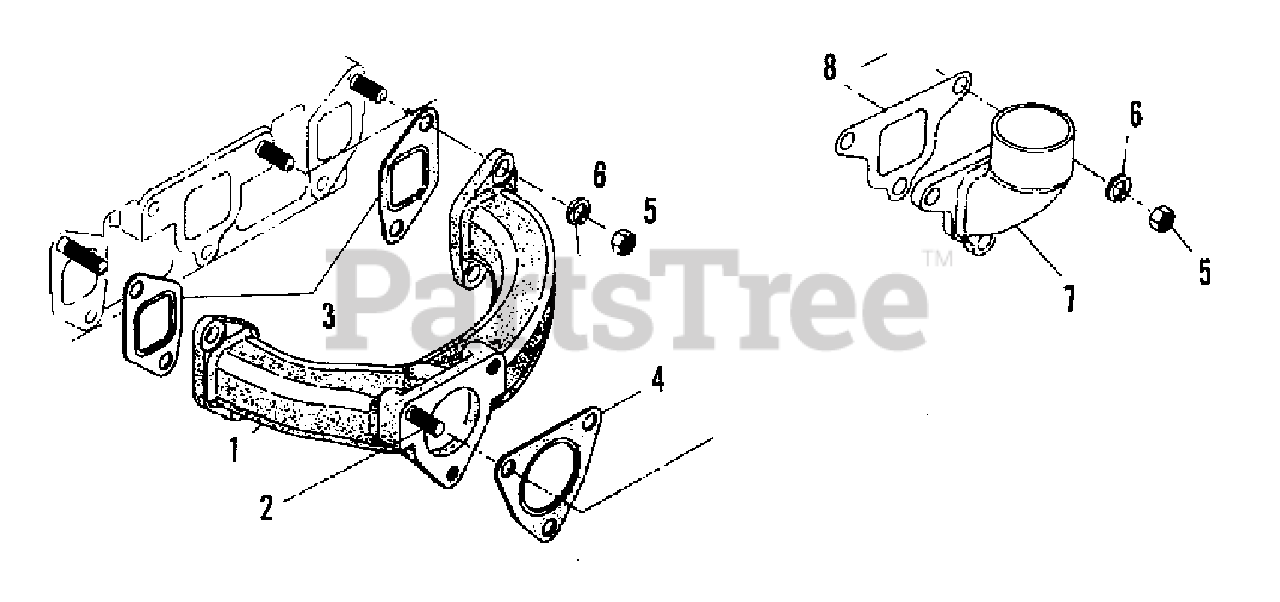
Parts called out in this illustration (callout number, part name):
2	STUD, M10 x 37
6	LOCKWASHER, M10
7	MANIFOLD, intake
